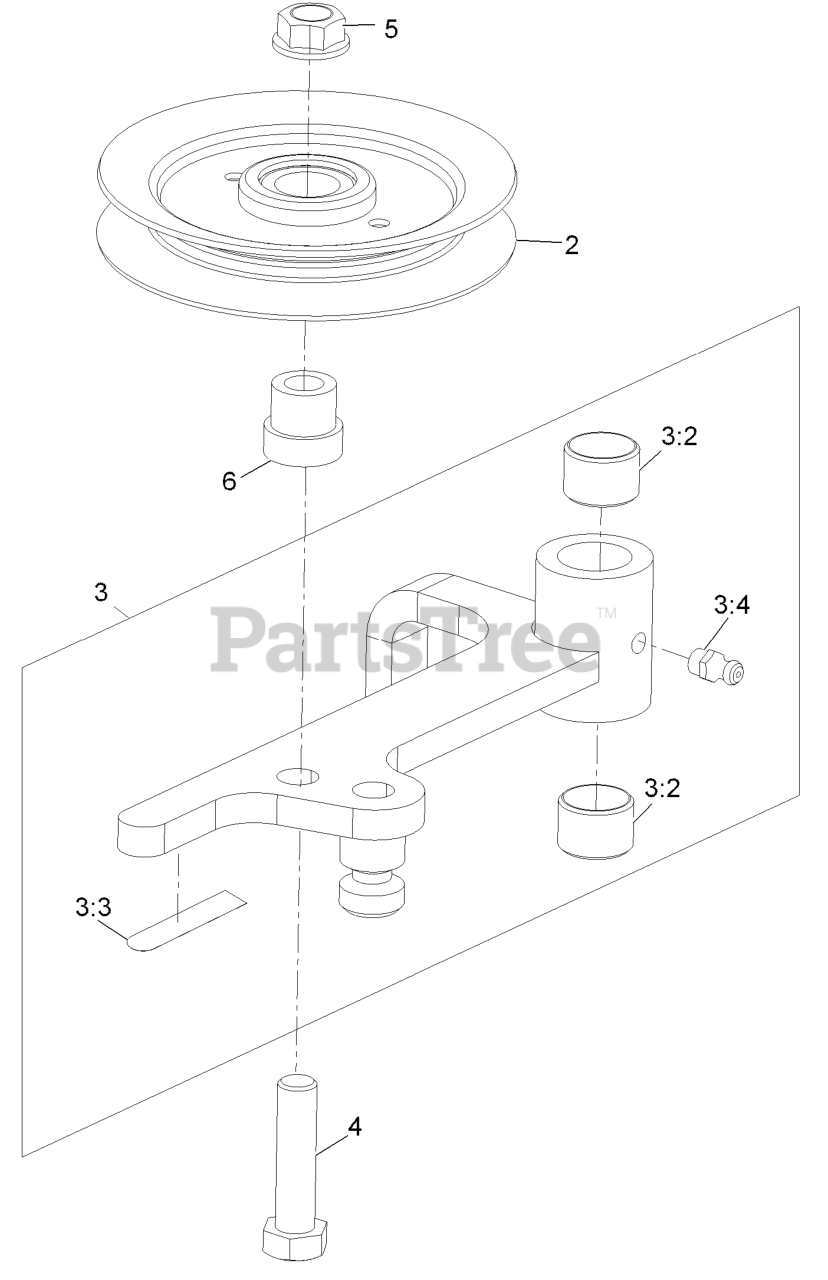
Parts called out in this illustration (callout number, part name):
2	Idler, Flat
3	Idler Assy With Bushings
3:2	Bearing
3:3	Decal-Warning
3:4	Zerk-1/4-28 Str
4	Screw-HH 3/8-16 X 1 1/2
5	Nut-Whizlock 3/8-16
6	Hub, Spacer
